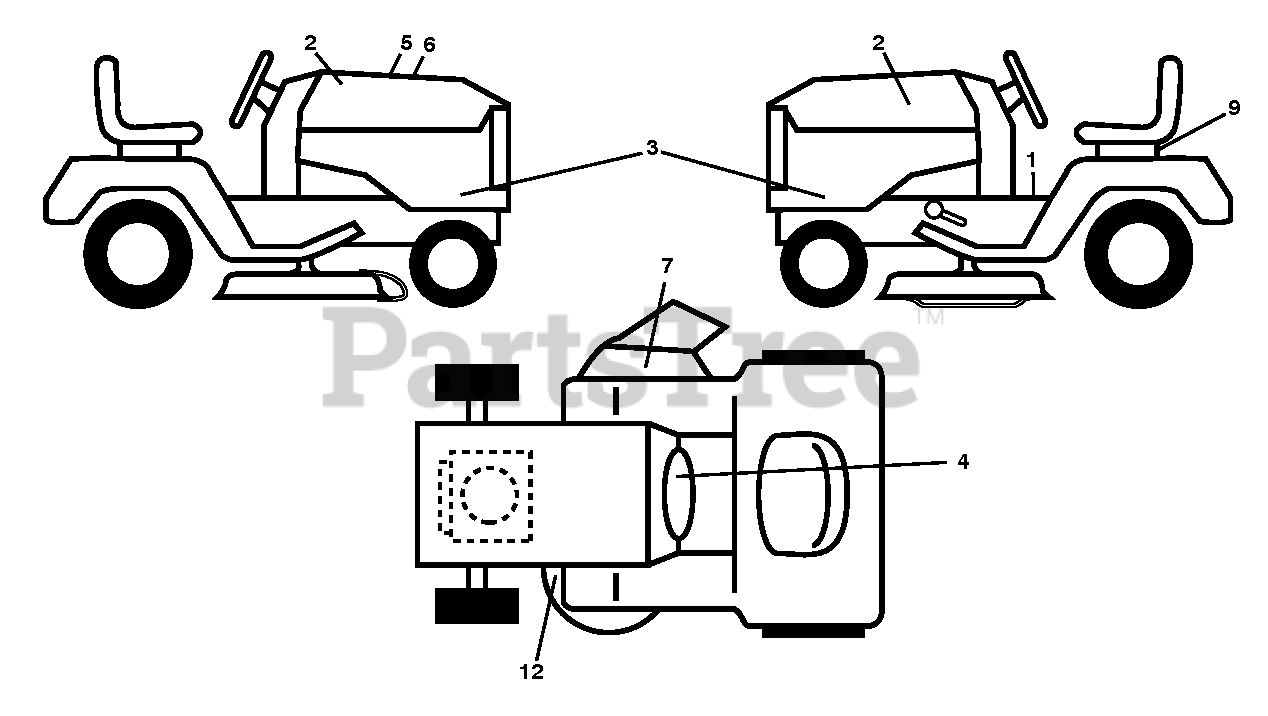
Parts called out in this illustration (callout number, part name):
1	DECAL.WARNING.2007.ENG/FR
2	DECAL.BADGE.170MM.TEXTLOGO.
3	DECAL.SIDE.PANEL.YTH18K46
4	DCL.WARNING.SPARK.IGNITION.CA
5	DECAL.WARNING.CUST.RESP.E85.
6	DECAL.RPL.KAW.FR.TLW.46E.K46L
7	DECAL, DECK DEFLECTOR, WARNING
9	DECAL BTRY SYMBOLS
12	DECAL.V-BELT.SCH.42/46"MEC/ELE
